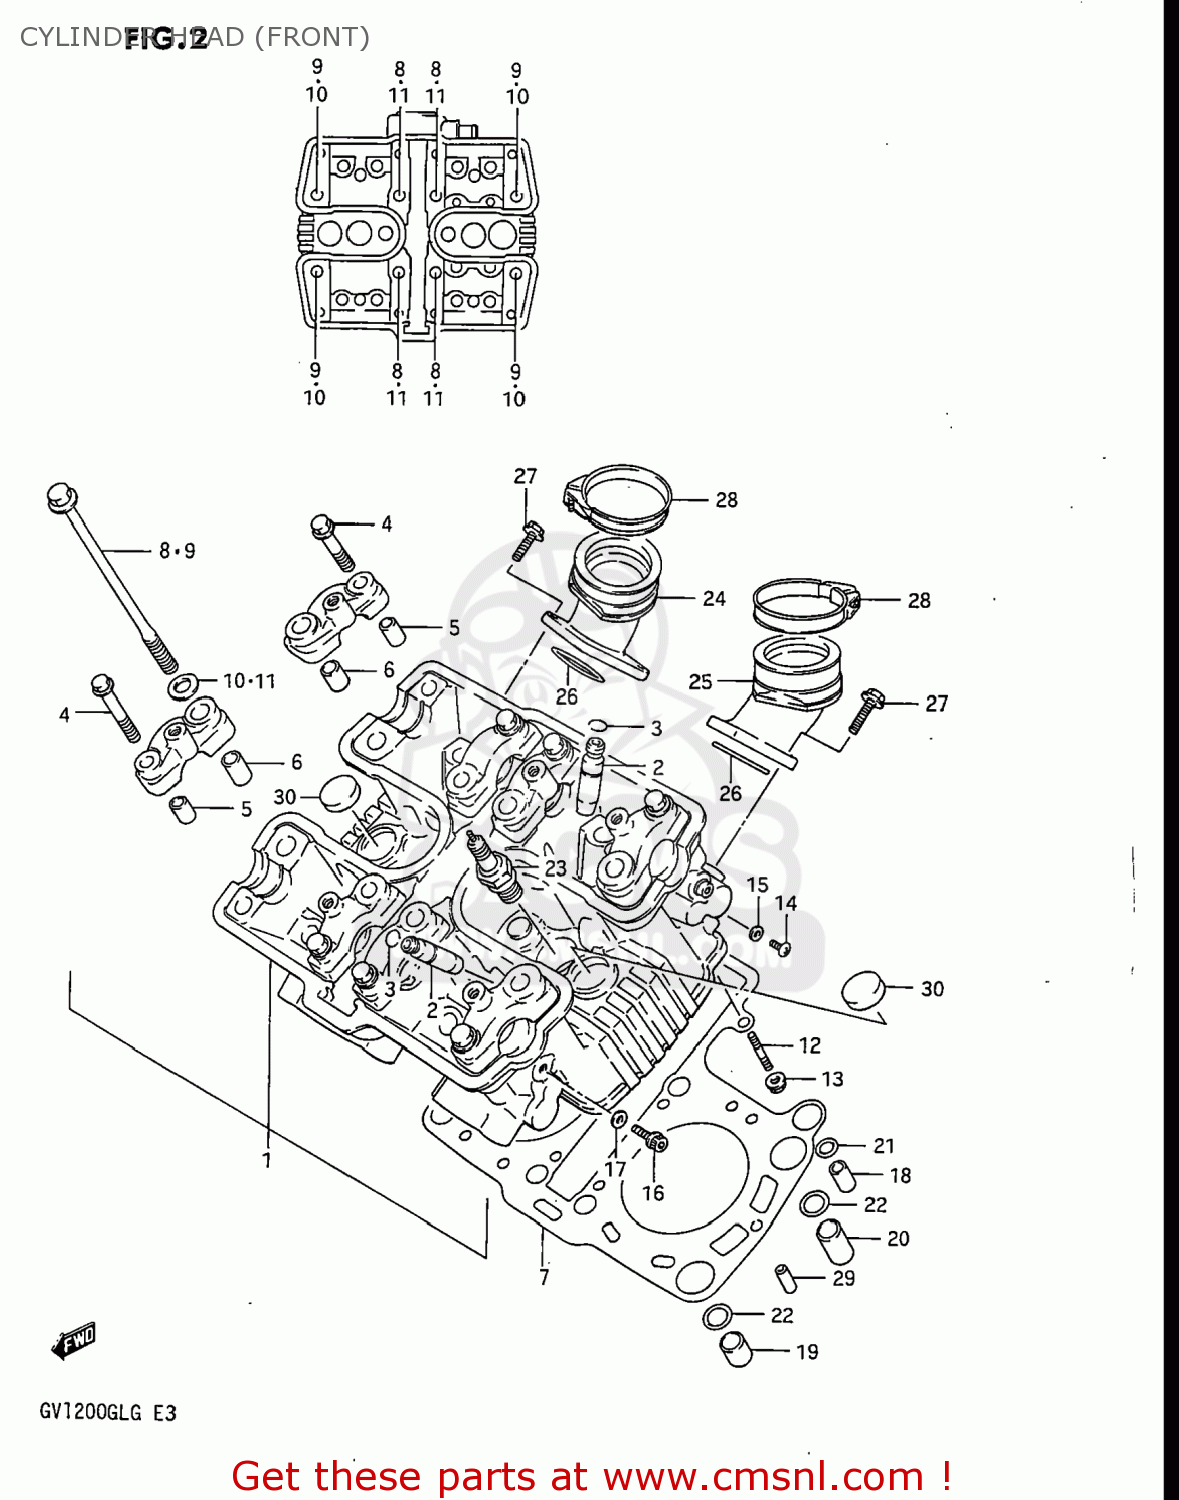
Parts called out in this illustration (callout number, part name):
1	HEAD ASSEMBLY,CYLINDER,FRONT
2	GUIDE,VALVE
3	RING,SNAP
4	BOLT
5	PIN (11X20)(SUS)
6	PIN(10.4X13X22)
7	GASKET,CYLINDER HEAD (MCA)
8	BOLT
9	BOLT
10	WASHER
11	WASHER (10X20X2.3)
12	STUD 6X25
13	NUT 6MM
14	SCREW
15	GASKET(5.3X9.3X1.2) (NAS)
16	BOLT
17	GASKET(6.2X13X1.2) (NAS)
18	PIN(6.4X9X20)
19	PIN
20	PIN
21	O RING(D:1.9,ID:8.6)
22	O RING(D:1.9,ID:12.6)
23	SPARK PLUG D8EA
24	PIPE,INTAKE
25	PIPE,INTAKE
26	O-RING (D:2.4 ID:39.7)
27	BOLT
28	CLAMP,PIPE
29	PIN
30	PLUG
